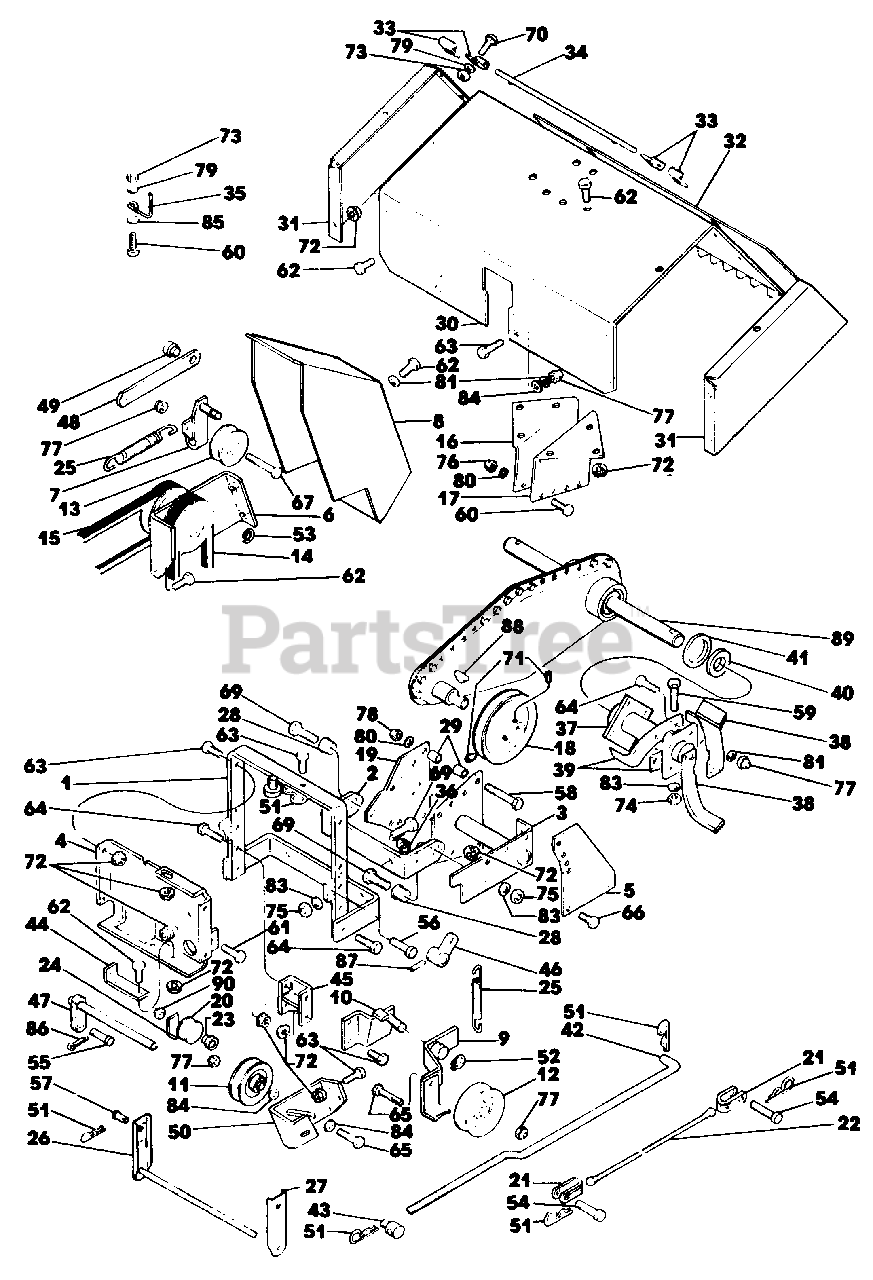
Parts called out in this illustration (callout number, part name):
1	Frame Assembly
2	Push Frame
3	Lift Frame Assembly
4	Plate
5	Lift Plate
6	Jackshaft Assembly
7	Idler Arm Assembly
8	Belt Guard Assembly
9	Idler Arm Assembly
10	Pivot Plate Assembly
11	V-Idler Pulley
12	Idler Pulley
13	Idler Pulley
14	V-Belt Primary Drive
15	V-Belt-Secondary Drive
16	Tine Shield Support R.H.
17	Tine Shield Support L.H.
18	Pulley-Tine
19	Side Plate Assembly
20	Nylon Roller
21	Clevis-Cable
22	Lift Cable
23	Spacer-Nylon Roller
24	Retainer Lift Cable
25	Spring
26	Belt Guide Assembly
27	Support Belt Guide
28	Bushing Pivot
29	Spacer
30	Tine Shield & Decal Assembly
31	Side Plate
32	Guard
33	Hinge
34	Rod
35	Belt Finger
36	Pyramidal Lock Washer
37	Tine Hub Assembly
38	Tine-R.H.
39	Tine-L.H.
40	Inner Felt Seal
41	Intermediate Felt Seal
42	Link-P.T.O.
43	Trunnion
44	Pivot Shaft Support
45	Pivot Extension Assembly
46	Clutch Arm Assembly
47	Pivot Shaft Assembly
48	Arm-Actuating
49	Pivot Bushing
50	Idler Bracket Assembly
51	Spring Clip
52	Snap Ring
53	"E" Ring
54	Clevis Pin
55	Clevis Pin
56	Clevis Pin
57	Clevis Pin
58	Cap Screw, Hex Hd. 1/4-28 x 2-3/4 Plated, Grade 5
59	Cap Screw, Hex Hd. 1/4-20 x 1" Plated, Grade 5
60	Cap Screw, Hex Hd. 5/16-18 x 3/4 Plated, Grade 5
61	Cap Screw, Hex Hd. 5/16-18 x 1-1/2 Plated, Grade 5
62	Cap Screw, Hex Hd. 3/8-16 x 3/4 Plated, Grade 5
63	Cap Screw, Hex Hd. 3/8-16 x 1" Plated, Grade 5
64	Cap Screw, Hex Hd. 3/8-16 x 1-1/2 Plated, Grade 5
65	Cap Screw, Hex Hd. 3/8-16 x 1-3/4 Plated, Grade 5
66	Cap Screw, Hex Hd. 3/8-16 x 7/8 Plated, Grade 5
67	Cap Screw, Hex Hd. 3/8-16 x 2-1/2 Plated, Grade 5
69	Cap Screw, Hex Hd. 1/2-13 x 1-1/2 Plated Grade 5
70	Bolt, Carriage 5/16-18 x 3/4 Plated
71	Setscrew, Hex Socket Hd. Cup Pt. 5/16-18 x 5/16
72	Nut, Hex Washer Hd. 3/8-16
73	Nut, Hex 5/16-18 Plated
74	Nut, Hex 7/16-20 Plated
75	Nut, Hex 1/2-13 Plated
76	Nut, Hex Cone Lock 1/4-20 Plated
77	Nut, Hex Cone Lock 3/8-16 Plated
78	Nut, Hex Cone Lock 1/4-28 Plated
79	Washer, Spring Lock 5/16 Plated
80	Washer, Spring Lock 1/4 Plated
81	Washer, Spring Lock 3/8 Plated
83	Washer, Spring Lock 1/2 Plated
84	Washer, Rat 3/8 Plated
85	Washer, Flat SAE 5/16 Plated
86	Pin, Cotter 1/8 x 3/4 Plated
87	Pin, Roll 3/16 x 1" Plated
88	Key, Hypro 3/16 x 3/4
89	Chain Case Assembly
90	Nut, Hex Cone Lock 5/16-18 Plated
